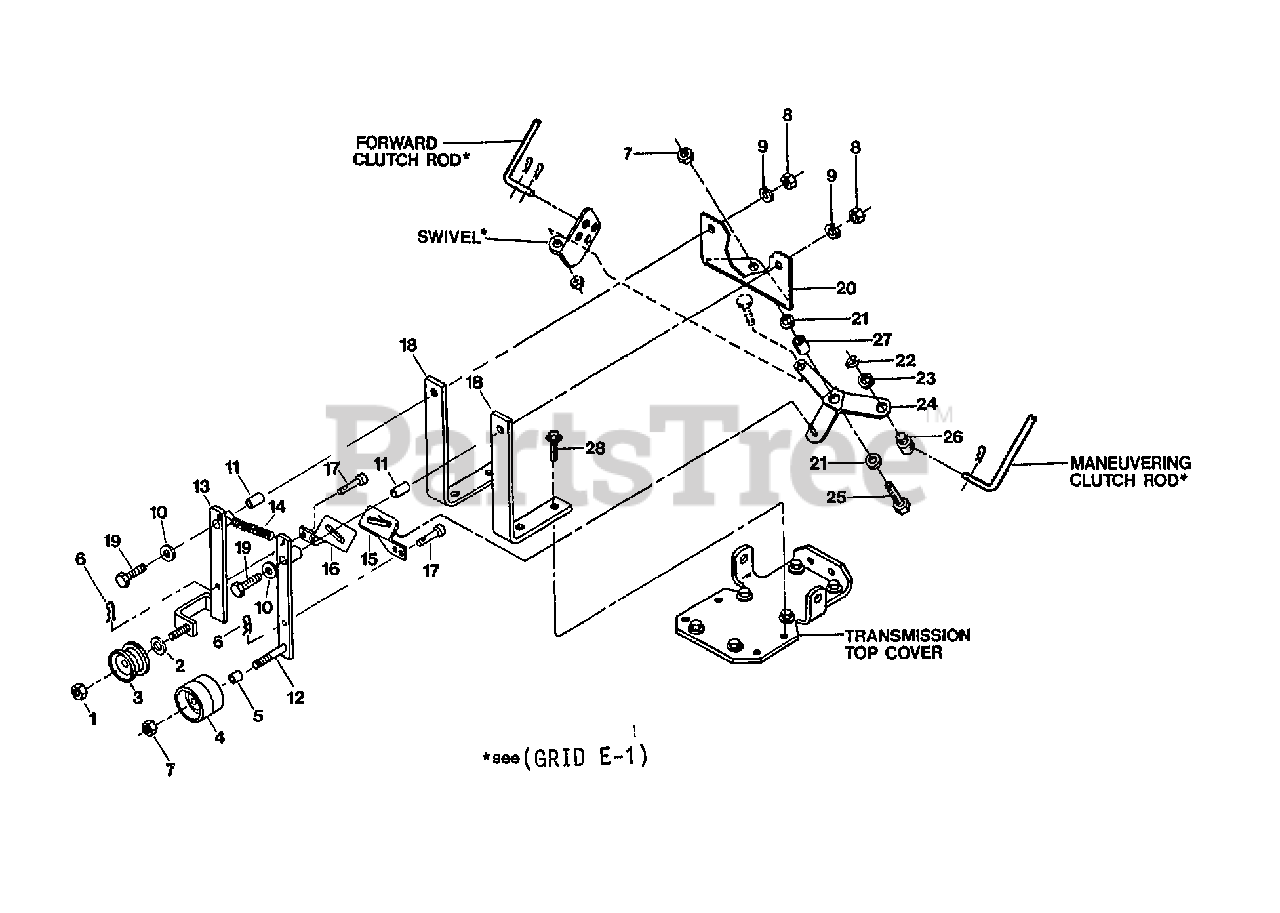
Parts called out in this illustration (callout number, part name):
1	NUT-LOCK 3/8-16 NYLON ZP
2	BUSHING-.54X.38X.08
3	IDLER-REV
3	PULLEY-IDLER REVERSE
4	PULLEY-FWD IDLER
5	BUSHING-.5X.375X.3
6	PIN-CLIP .08
7	NUT-H/LK 3/8-16
8	NUT-HEX 5/16-18 ZP
9	WASHER-LK .312 ZP
10	WASHER-#.75X.32X.09 ZP
11	BUSHING-.438X.323X.712
12	ARM-IDLER FWD PNT
13	IDLER-REV
13	ARM-IDLER REV RED
14	SPRING-.436 X 3.25
15	LINK-FWD
17	PIN-CLEVIS .375X.719 ZP
18	MOUNT BAR-PNT (20691)
19	SCR-HH 5/16-18X2.25 G5ZP
20	SHIFT BASE-OPC PNT
21	SPACER-.88X.385X.09 ZP
22	RING-KLIP .500 ZINC
23	WASHER-#.88X.51X.063 ZP
24	BELLCRANK-OPC PNT
25	SCR-HH 3/8-16X1.25
26	PIVOT-ROD
27	BUSHING-.5X.38X.4
28	SCR-HFLK 5/16-18X1.00 ZP
